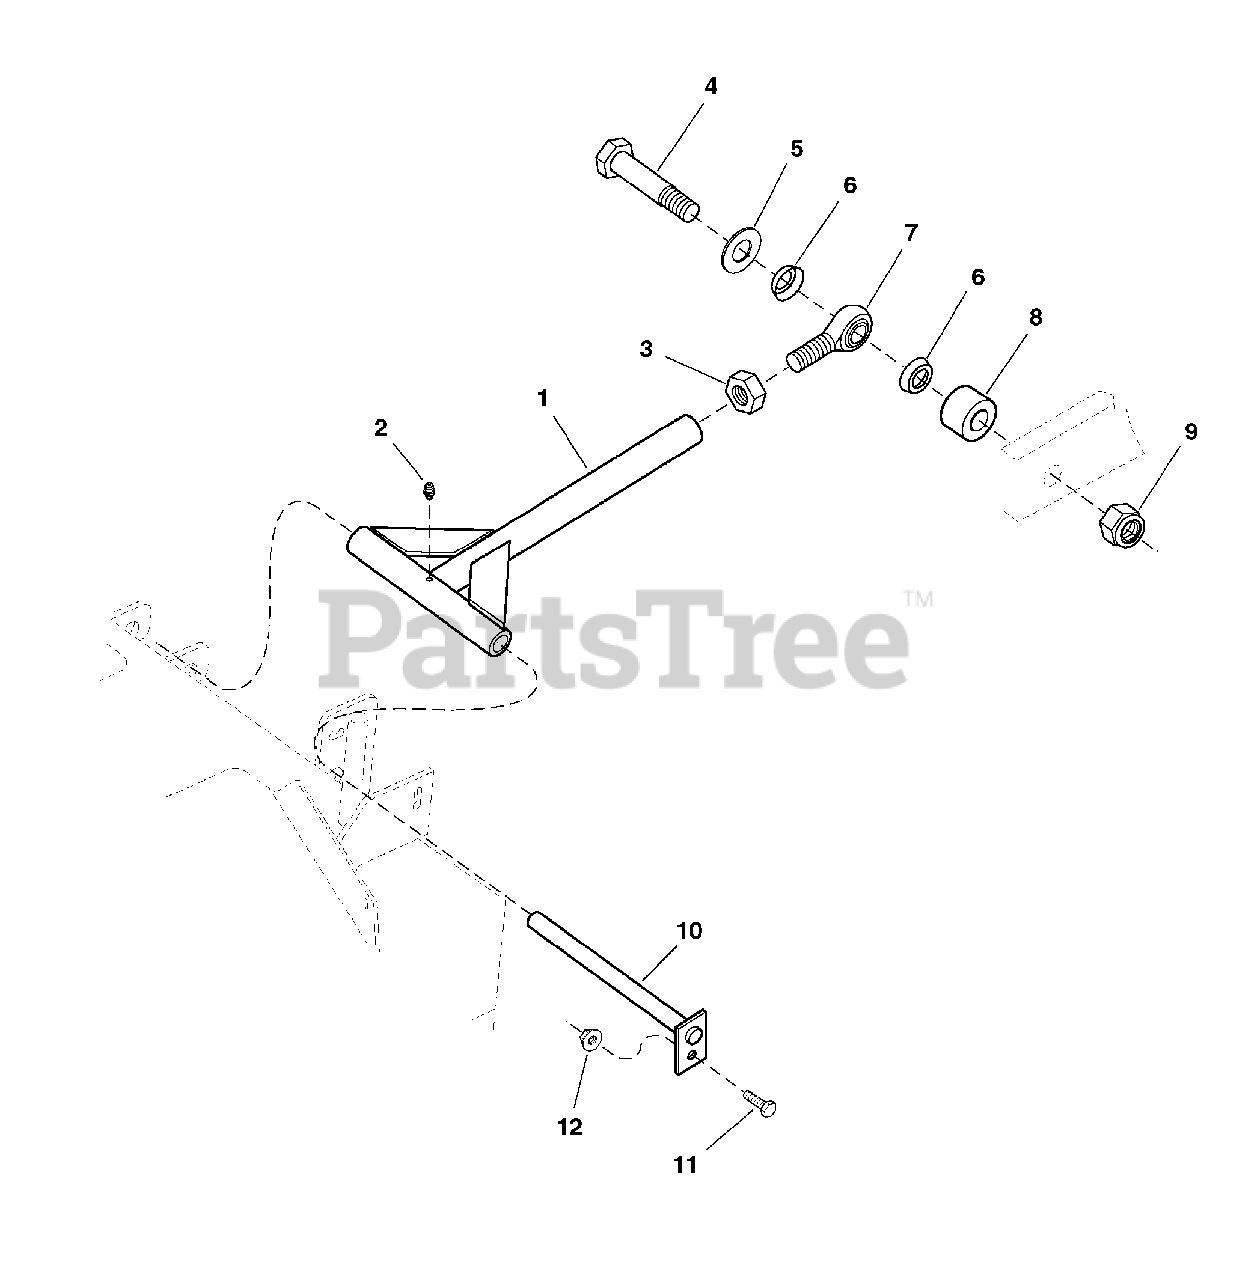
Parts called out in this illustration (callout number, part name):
1	DECK PUSHER BAR
2	GREASE FITTING
3	NUT, Hex, Jam, 3/4-16
4	CAPSCREW, Hex Hd, 3/4-16 x 4
5	WASHER, 3/4
6	ROD END SEAL
7	BALL JOINT, 3/4-16
9	NUT, Hex, Nylon Lock, 3/4-16
10	PUSH BAR MOUNT
11	CAPSCREW, Hex Hd, 5/16-18 x 1
12	NUT, Hex, Serrated Flange, 5/16-18
